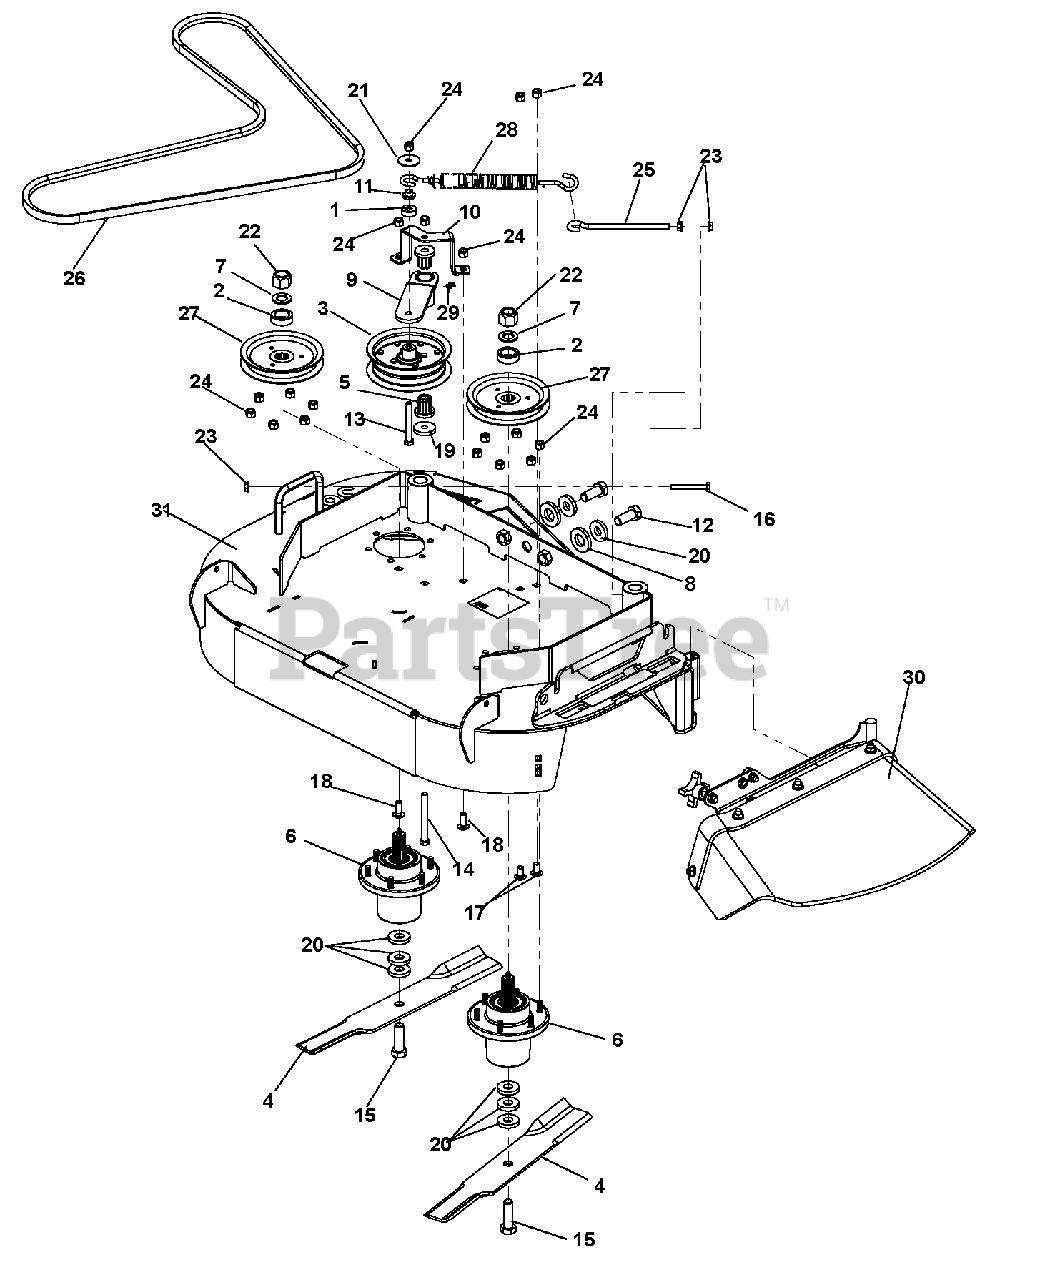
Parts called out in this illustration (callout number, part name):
1	Bushing, .380 x 1.00 x .410
2	Spacer, 1.500 x 1.000 x .510 (SN 000101 – 020999)
3	Pulley, Flat 5.0 x .38 w/BRG
4	Blade, 18"
5	Bearing, Flange M10 x M25 x M27 Fluted
6	Assembly, Spindle S/O
7	Washer, .75 x 1.313 x .113
8	Washer, .905 x 1.75 x .250
9	Weldment, Idler Arm w/Offset
10	Bracket, Idler Support
11	Bushing, Flange .385 x .500 x .875 x .406
12	Bolt, Hex .625-11 1.50 Grade 8
13	Bolt, .38-16 x 3.00 Hex Grade 5
14	Bolt, .38-16 x 3.75 Hex Grade 5 (SN 000101 – 020999)
15	Bolt, .62-11 x 2.00 Hex Grade 8
16	Bolt, .31-18 x 2.50 Hex Grade 8
17	Bolt, Round Head Square Neck .38-16 x .75
18	Bolt, .38-16 x 1.00 Round Head Square Neck Grade 5
19	Washer, .406 x 1.50 x .245 Flat
20	Washer, .630 x 1.50 x .25 Flat
21	Washer, .380 x 1.50 x .062 Flat
22	Locknut, .75-16 Crown Grade 5
23	Nut, Spinlock Flange .312-18
24	Nut, Locking-Nylon .38-16
25	Bolt, Eye .31-18 x 5.50 .62 DIA
26	Gravely 36" Drive Belt
27	Pulley, Spline Spindle (SN 000101 – 021000)
28	Spring, Extension
29	Fitting, .25-28 Straight Grease Zerk
30	Discharge Shield Assembly (see page 23 for individual parts)
31	Assembly, Deck 36" with Decals
